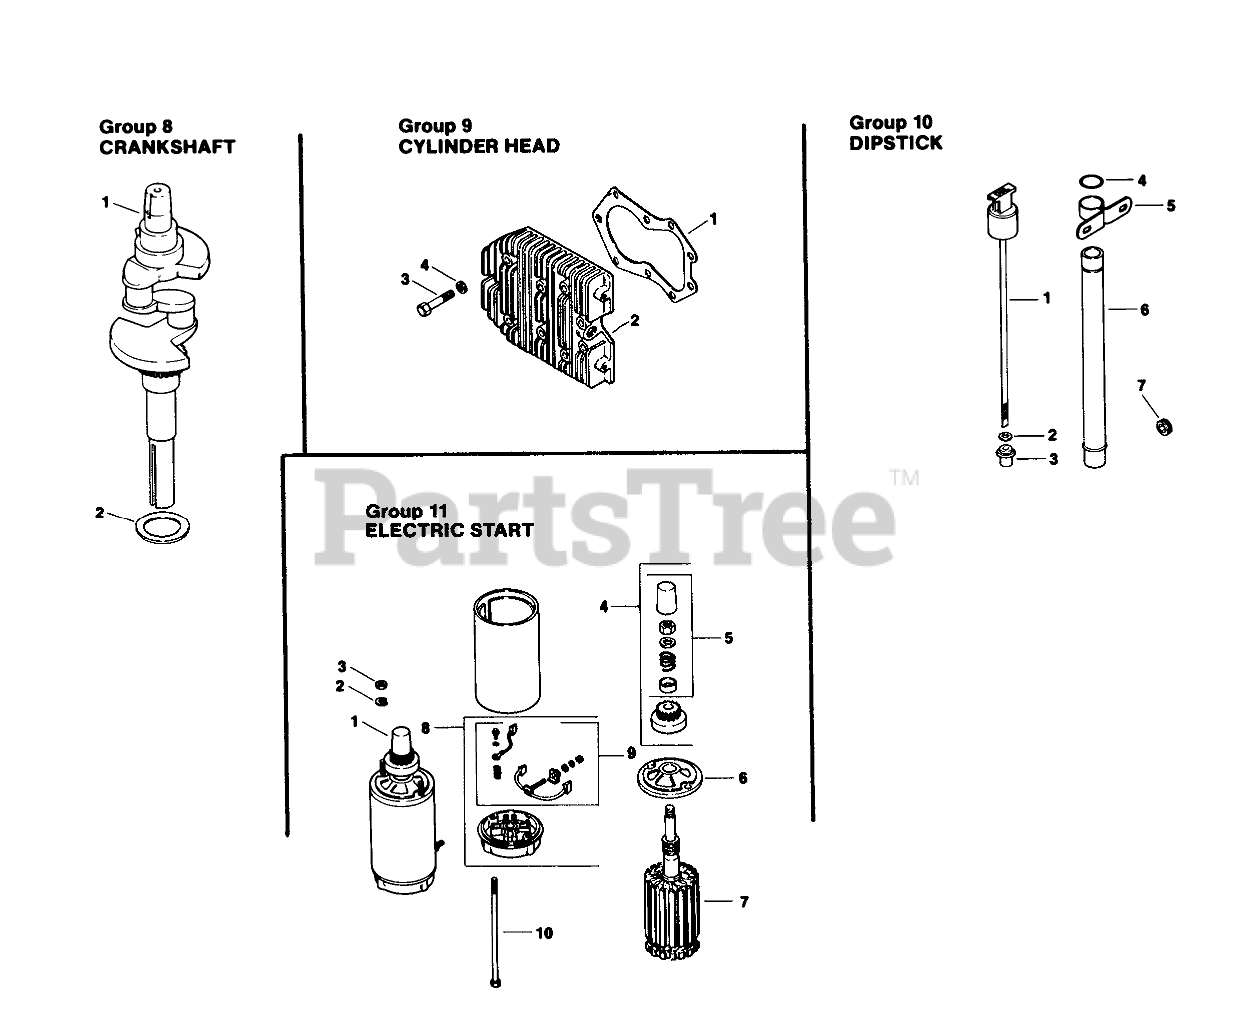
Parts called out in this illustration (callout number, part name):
1	Crankshaft
1	Gasket-Head
1	Dipstick
1	Starter Assembly (Incl. Ref. #4-10)
2	Washer-Thrust .119/.122
2	Washer-Thrust .128/.131
2	Washer-Thrust .137/.140 CYLINDER HEAD GROUP 9
2	Head-Cylinder
2	Screw
2	Washer
3	Screw-Hex Hd.
3	Seal-Rubber
4	Washer
4	Kit-Drive
5	Bracket-Oil Tube Support
5	Kit-Drive Parts
6	Tube-Oil Fill
6	Cap-Drive End
7	Plug, Pipe
7	Armature
8	Cap, Comm. End
9	Kit-Brush
20	Seal-Rear Oil
28	Screw-Hex Washer Hd.
